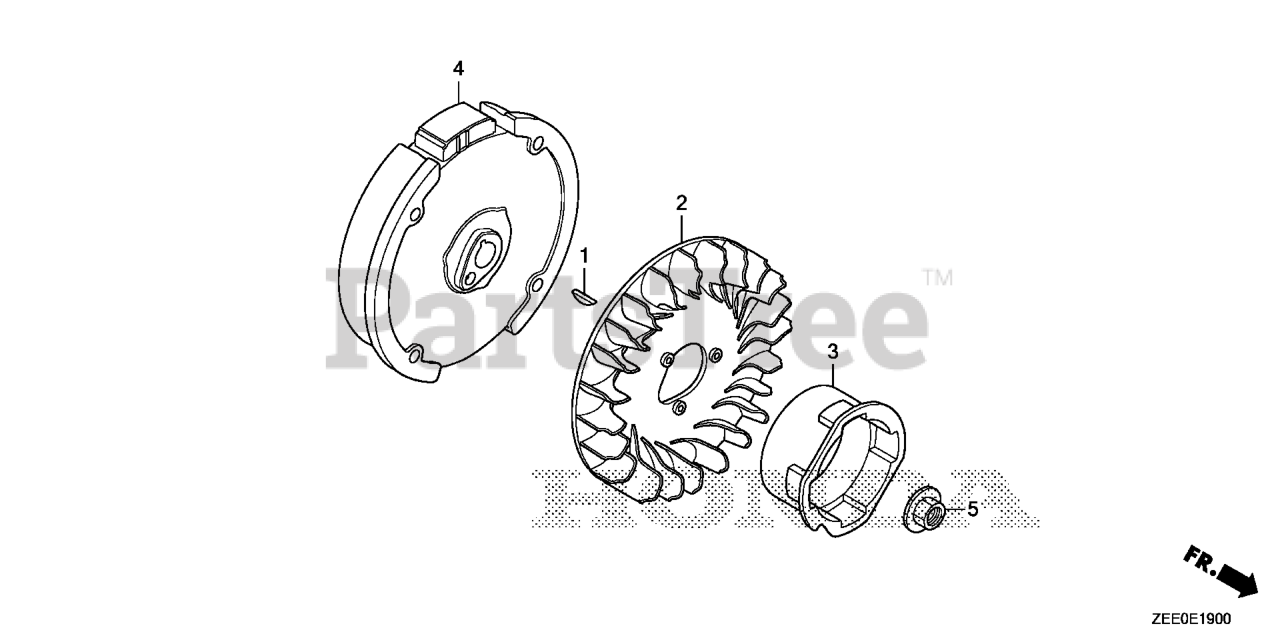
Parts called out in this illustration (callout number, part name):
1	KEY, SPECIAL WOODRUFF (25X18)
2	FAN, COOLING
3	PULLEY, STARTER
5	NUT, SPECIAL (14MM)
